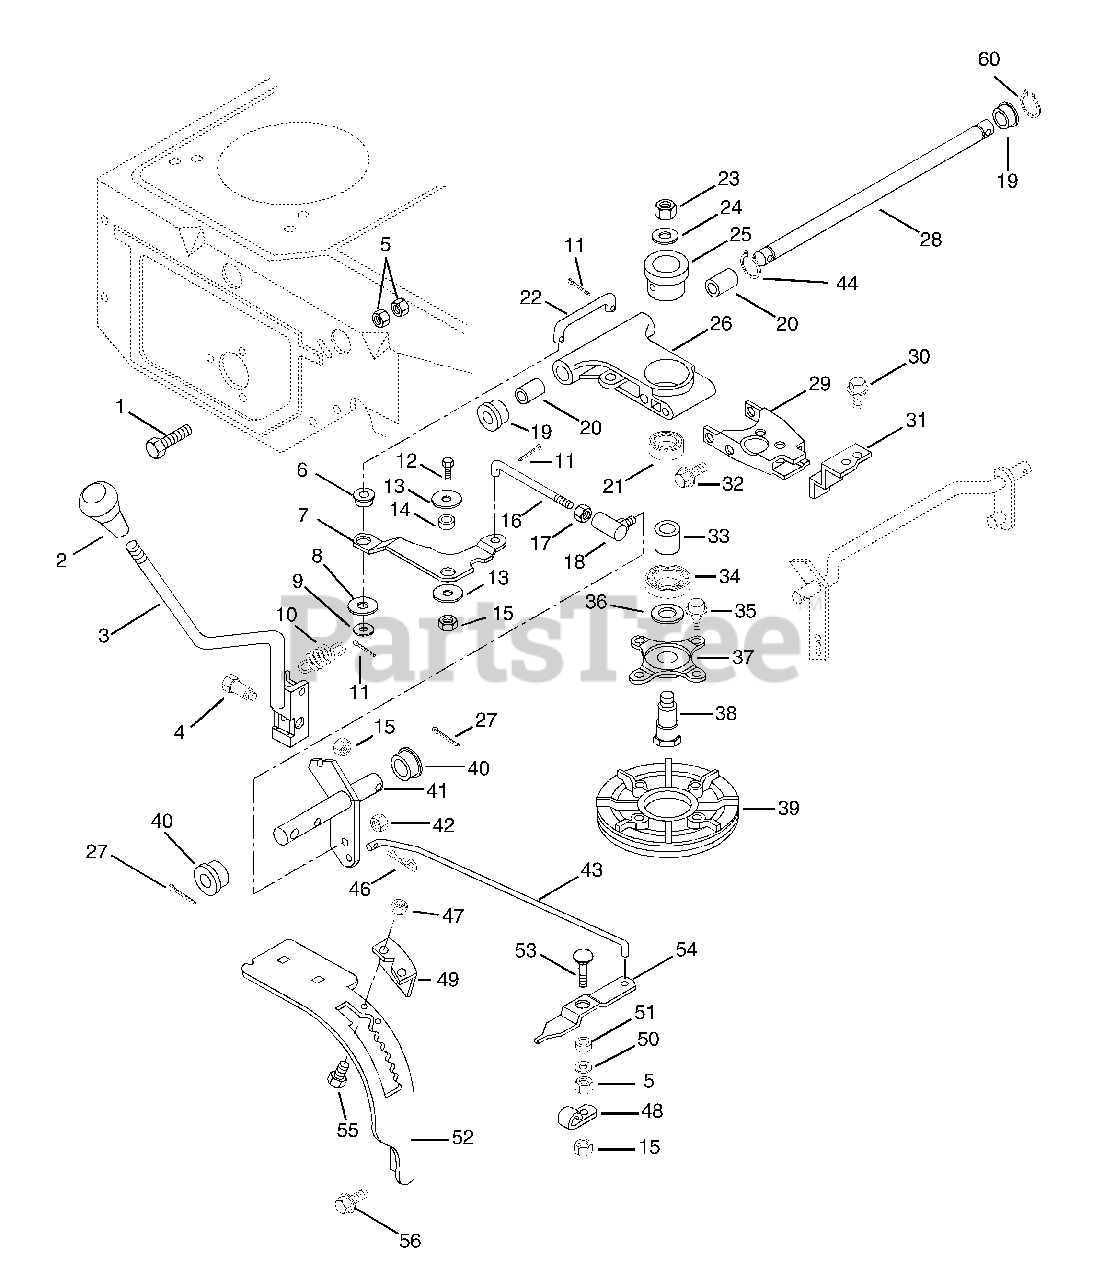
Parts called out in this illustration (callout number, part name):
1	BLT-HEX .31-18X1.50 GR2 YWZC
3	SHIFT LEVER
4	SHOULDER BOLT .436 X .912
5	@NUT-HEX .31-18 YWZC
6	BSHG-FLG .372X.500X.312X.625NY
7	BELL CRANK
8	@WSHR-FL-STL.531X1.06X.095YWZC
9	WSHR-FL-STL .380X.626X.033
10	SG-TENS .092X.69X1.75 WLD 54
11	@PIN-CTR .09X.75 EXTPRSQCT YWZ
12	@BLT-HEX .31-18X.75 GR5 YWZC
13	WSHR-FL-STL .344X1.375X.075YWZ
14	SPACER BUSHING .5 X .32 X .21
15	@NUT-LK-CTR .31-18 YWZC
16	SHIFT ROD
17	NUT-JAM .375-24 LH YWZC
18	BALL JOINT- SNAP IN
19	FLANGE BUSHING
20	BSHG-SLV .625X.750X.500 BR
21	BRG-BALL .625X1.375X.44
22	SHIFT LINK
23	NUT-LK-CTR .50-20 YWZC
24	WSHR-HDND-STL-THR.515X.97X.062
25	BEARING HOUSING
26	CARRIER ASSEMBLY
27	@PIN-CTR .12X1.00 EXTPRSQCT YZ
28	TRANSFER SHAFT
29	CARRIER YOKE
30	@SCR-TAP .31-18X.50 HWH TR YWZ
31	NEUTRAL STOP
32	@SCR-TAP .31-18X.75 HWH TR YWZ
33	BSHG-SLV .634X1.000X.465
34	BRG-BALL .750X1.781X.61
35	@SCR-TAP .25-20X.50 HWH TR YWZ
36	WSHR-HDND-THRST .758X1.23X.031
37	DISC ADAPTER
38	SPINDLE BOLT
39	DRIVE CARRIER ASSEMBLY
40	FLANGE BUSHING
41	SHIFT ARM
42	NUT-CTRLK .31-24 YWZC
43	INDICATOR ROD
44	RG-RTNG-EXT .625X.035
45	@NUT-HEX .25-20 YWZC
46	PIN-COTR .06X.50
47	@NUT-LK-CTR .25-20 YWZC
49	BRACKET- NEUTRAL
50	WSHR-FL-STL .323X.625X.062 YWZ
51	SPACER BUSHING .5 X .32 X .163
52	QUADRANT
53	BLT-RDHDSQNK .31-18X1.0 SHTYZ
54	INDICATOR
55	@BLT-HEX .25-20X.50 GR5 YWZC
56	@SCR-TAP .25-20X.50 HWH TR YWZ
